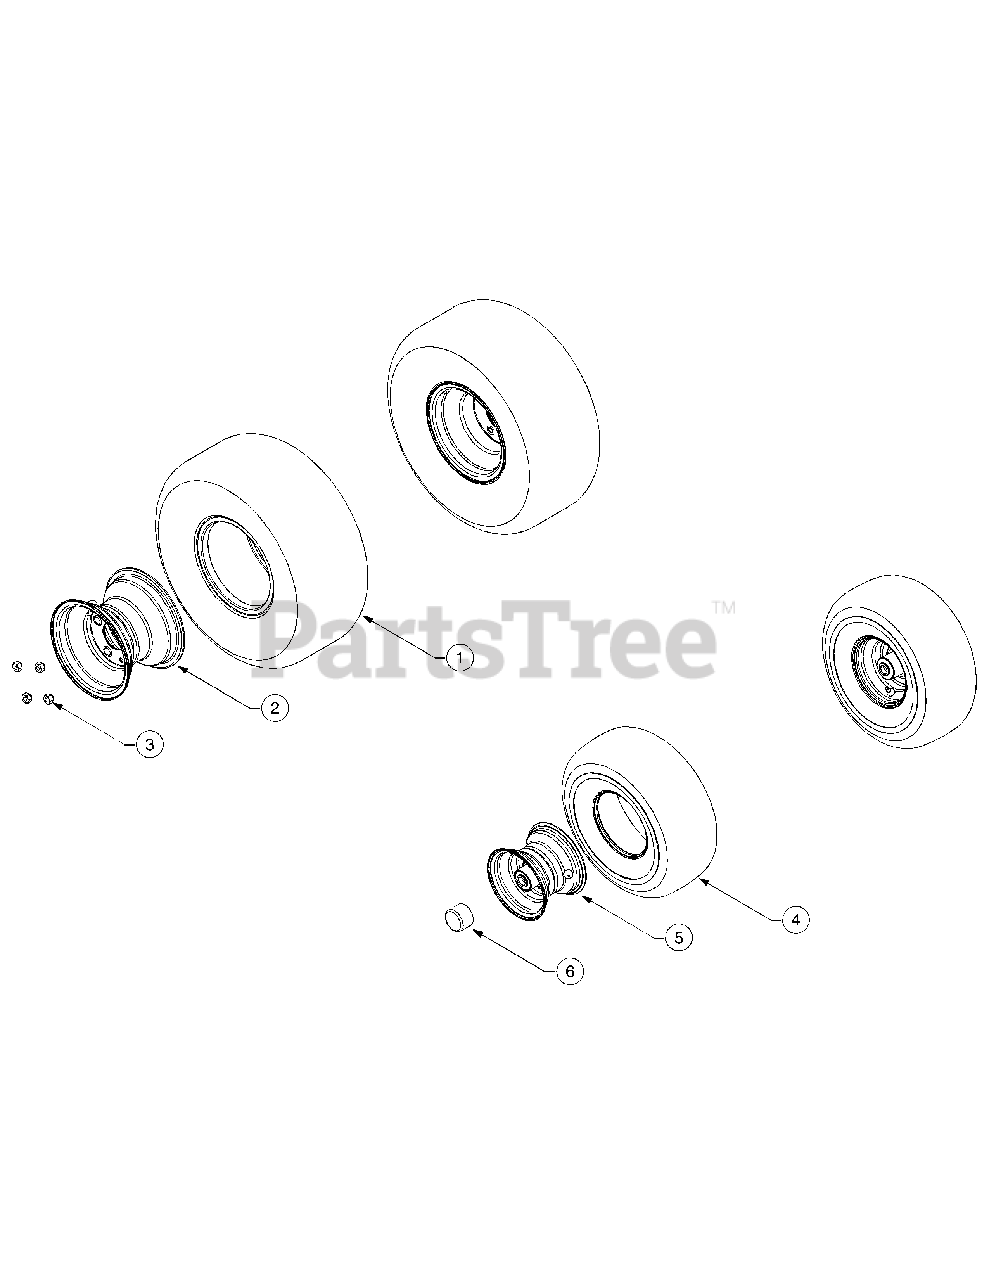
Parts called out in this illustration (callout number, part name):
1	Wheel Ass’y, Complete, 22 x 9.5 x 12
1	Tire, Turf, 22 x 9.5 x 12
2	Rim Assembly,
3	Lug Nut, 7/16-14
4	Wheel Ass’y, Complete, 15 x 6 x 6
4	Tire, Turf, 15 x 6 x 6
5	Rim Assembly, 6 x 4.5
